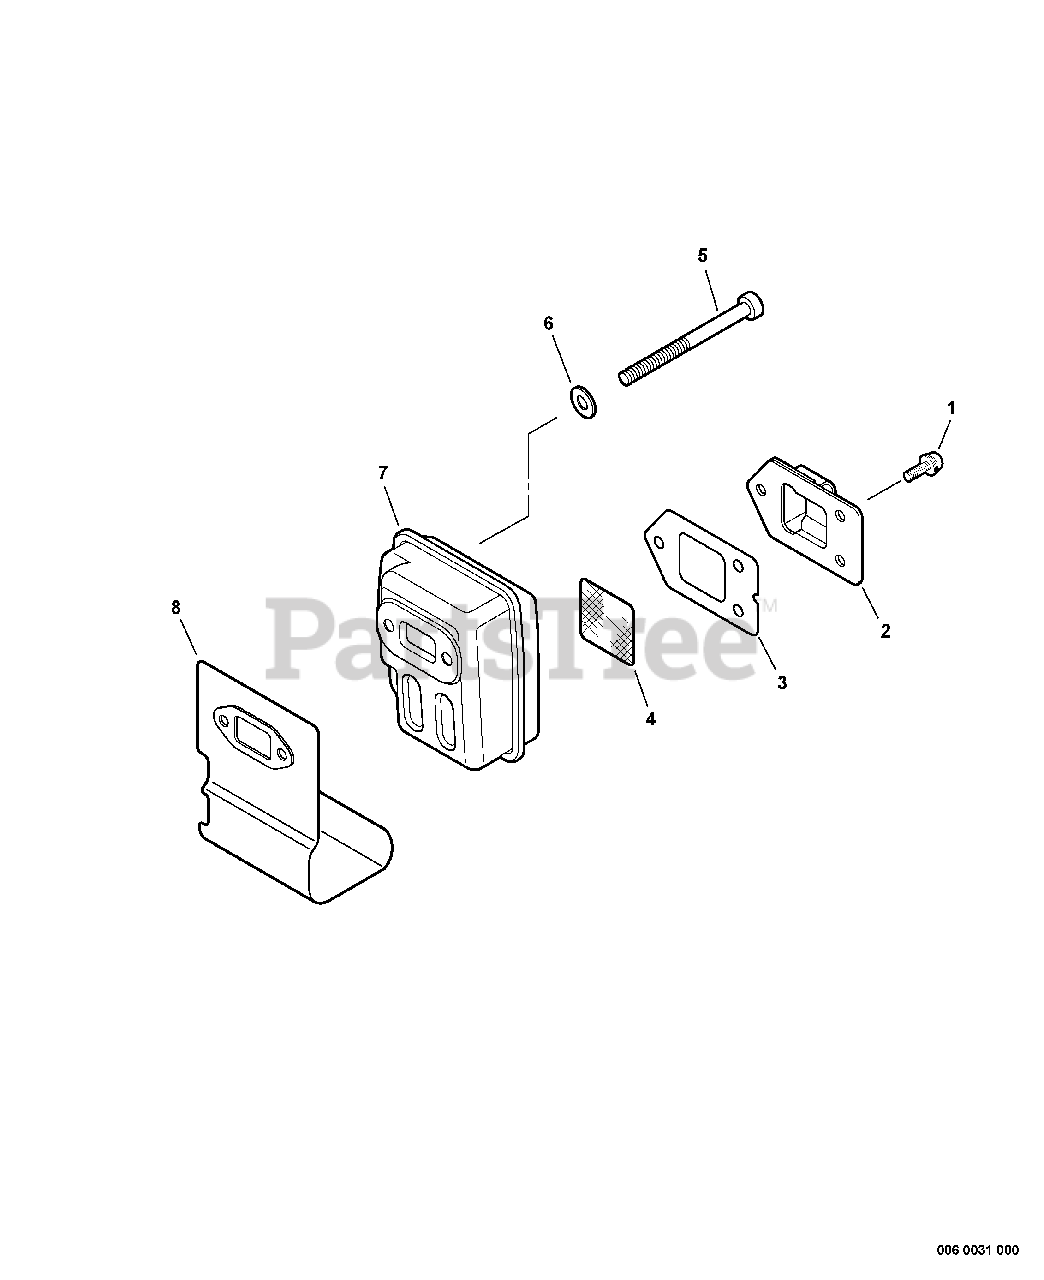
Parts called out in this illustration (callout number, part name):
1	SCREW - 4X10
2	GUIDE, EXHAUST
3	GASKET, EXHAUST
4	SCREEN, SPARK ARRESTOR
5	SCREW - 5X50
6	WASHER - 5
8	SHIELD, EXHAUST
